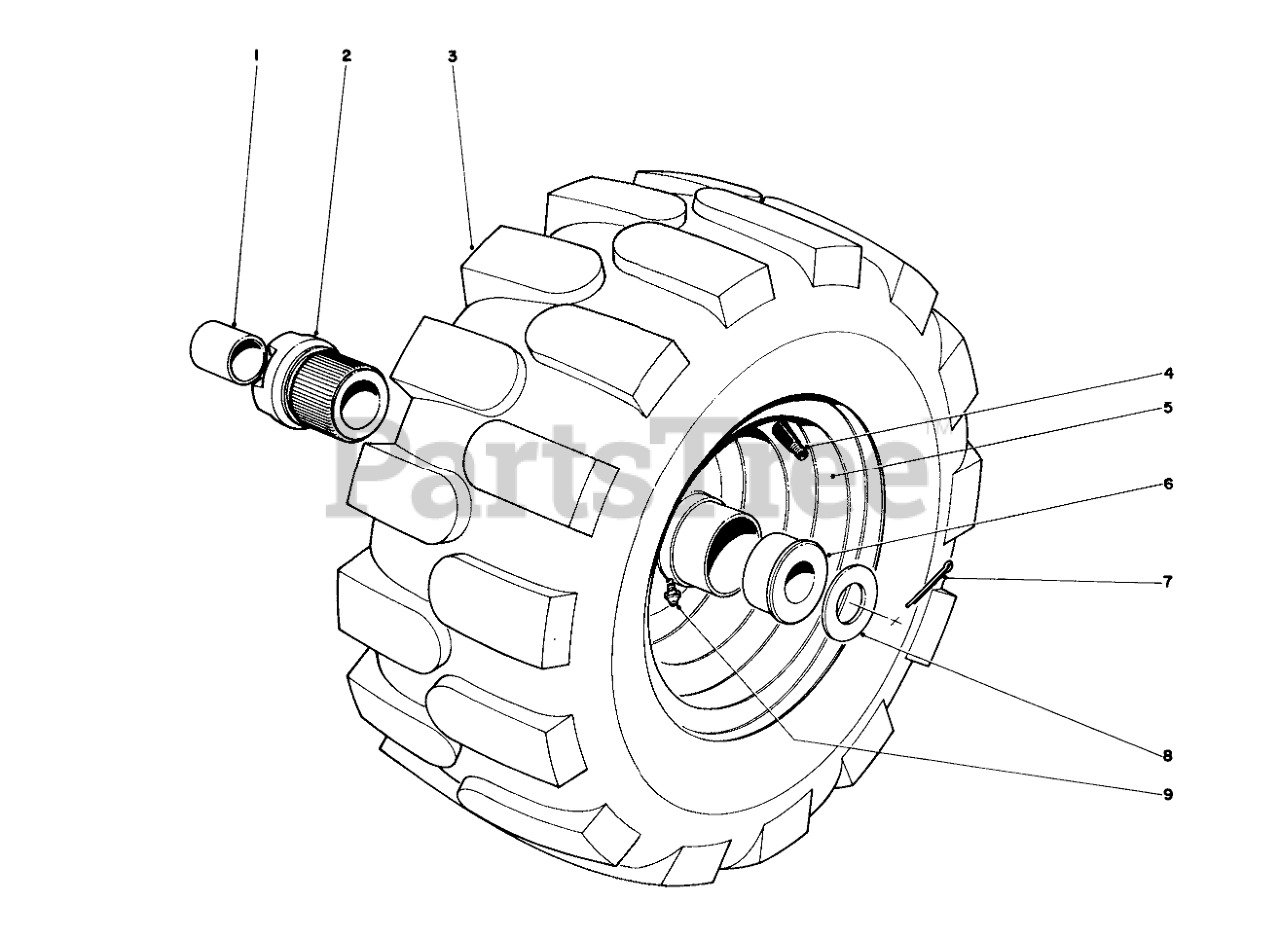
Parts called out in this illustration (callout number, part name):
1	.877ID X .750LG BSHG
2	JAW HUB
4	STEM-VALVE
5	Wheel Rim
6	Bushing
7	PIN-COTTER
8	WASHER-THRUST
9	FITTING-GREASE
